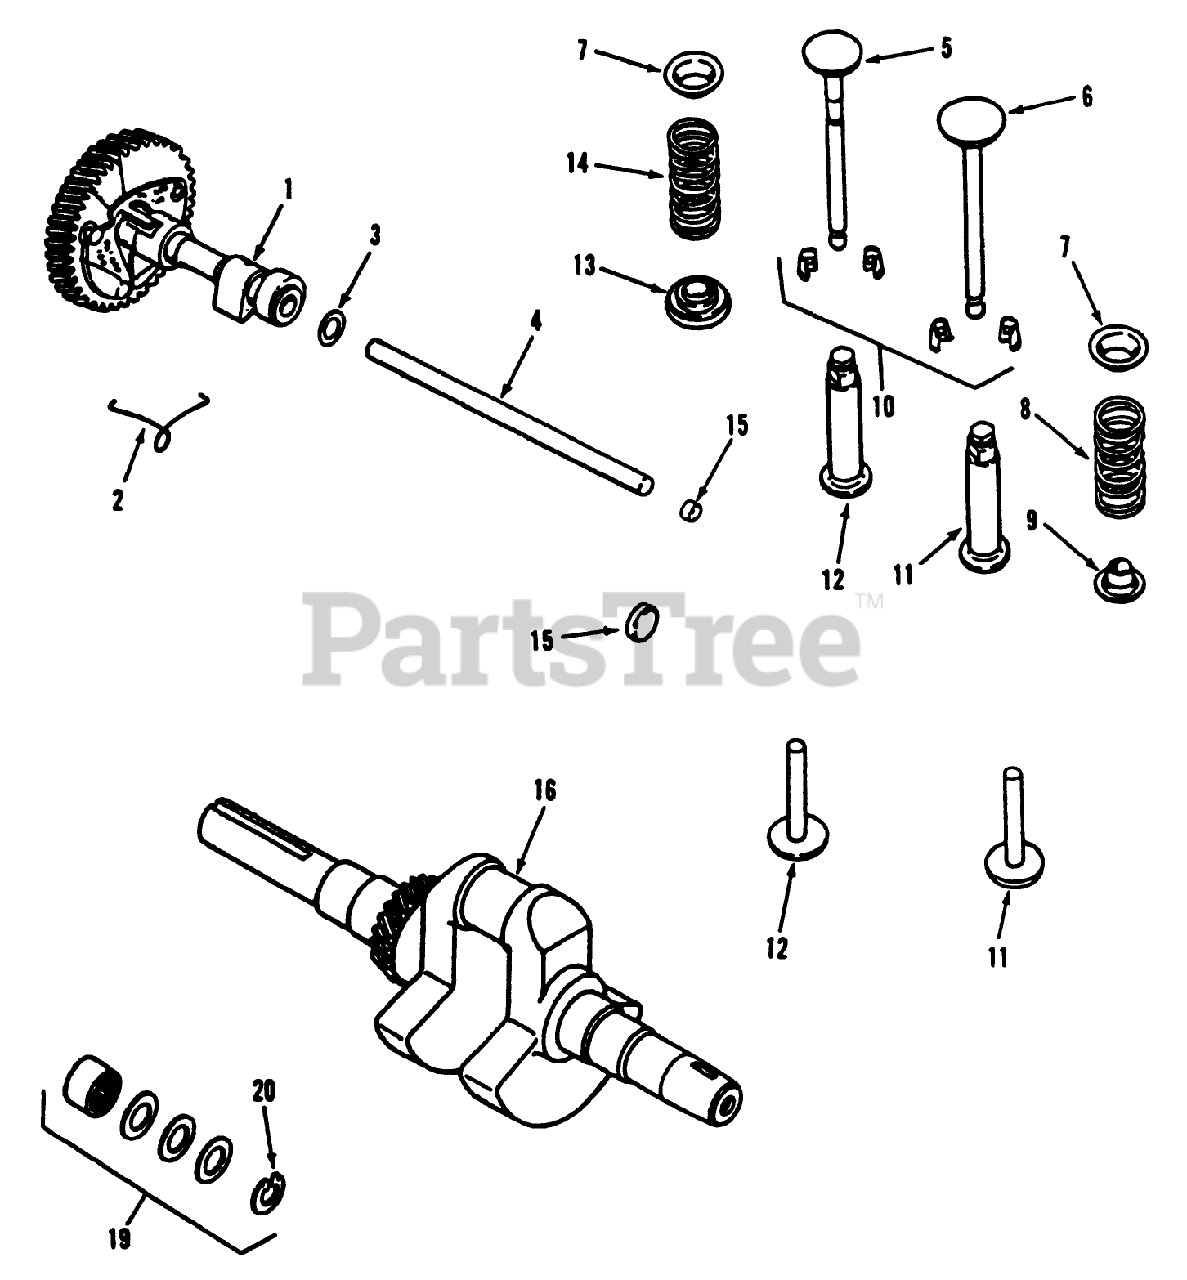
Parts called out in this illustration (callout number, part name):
1	KOHLER 47-010-11
2	KOHLER 47-089-01
3	KOHLER 275066
4	KOHLER 47-380-09
5	KOHLER 235838
6	KOHLER 235008
7	KOHLER 235011
8	KOHLER 235010
9	KOHLER 230011
10	KOHLER 41-755-10
11	KOHLER D-235327
12	KOHLER D-235327
13	KOHLER 52-413-01
14	KOHLER 235168
15	KOHLER X-702-3
16	KOHLER 47-142-02
19	KOHLER 47-755-01
20	KOHLER X-269-34
